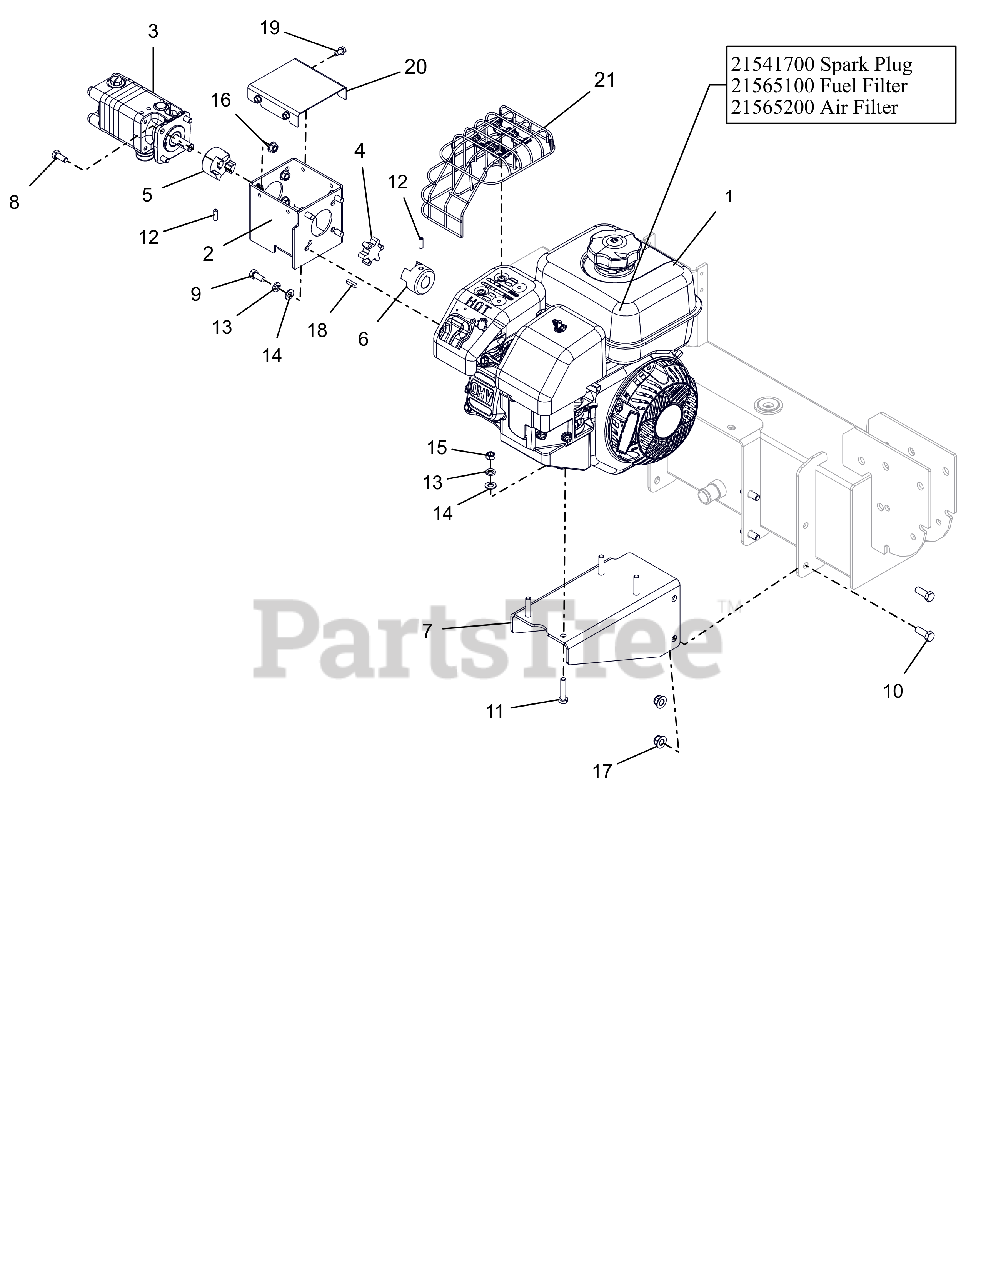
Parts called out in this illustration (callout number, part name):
1	ENGINE, KOHLER SH265 (CARB)
1	PLUG, SPARK
1	FILTER, FUEL (IN TANK)
1	FILTER, AIR
2	WLDMT, PUMP MOUNT BRKT
3	PUMP,SPLITTER-13 GPM
4	SPIDER - URETHANE
5	COUPLER - DRIVE 1/2"
6	COUPLER - DRIVE, 3/4"
7	MOUNT-ENGINE
8	@BLT-HEX .31-18X.75 GR5 YWZC
9	BLT-HEX .31-24X.75 YWZC GR5
10	@BLT-HEX .38-16X1.00 GR5 YWZC
11	@BLT-HEX .31-18X1.50 GR5 YWZC
12	SCR,SET .25-20X.75 PCPT SH
13	WSHR-LK .312X.097 HVY YWZC
14	@WSHR-FL-STL.344X.688X.065YWZC
15	@NUT-HEX .31-18 YWZC
16	@NUT-LK-TOP-FLG .31-18 YWZC
17	@NUT-LK-NYL-FLG .38-16 YWZC
18	KEY-SQ .188X.75X.188
19	SCR-TAP .25-20X.50 HWH TR YWZ
20	COVER W/DECALS
21	BASKET-WIRE-KOHLER SH265
